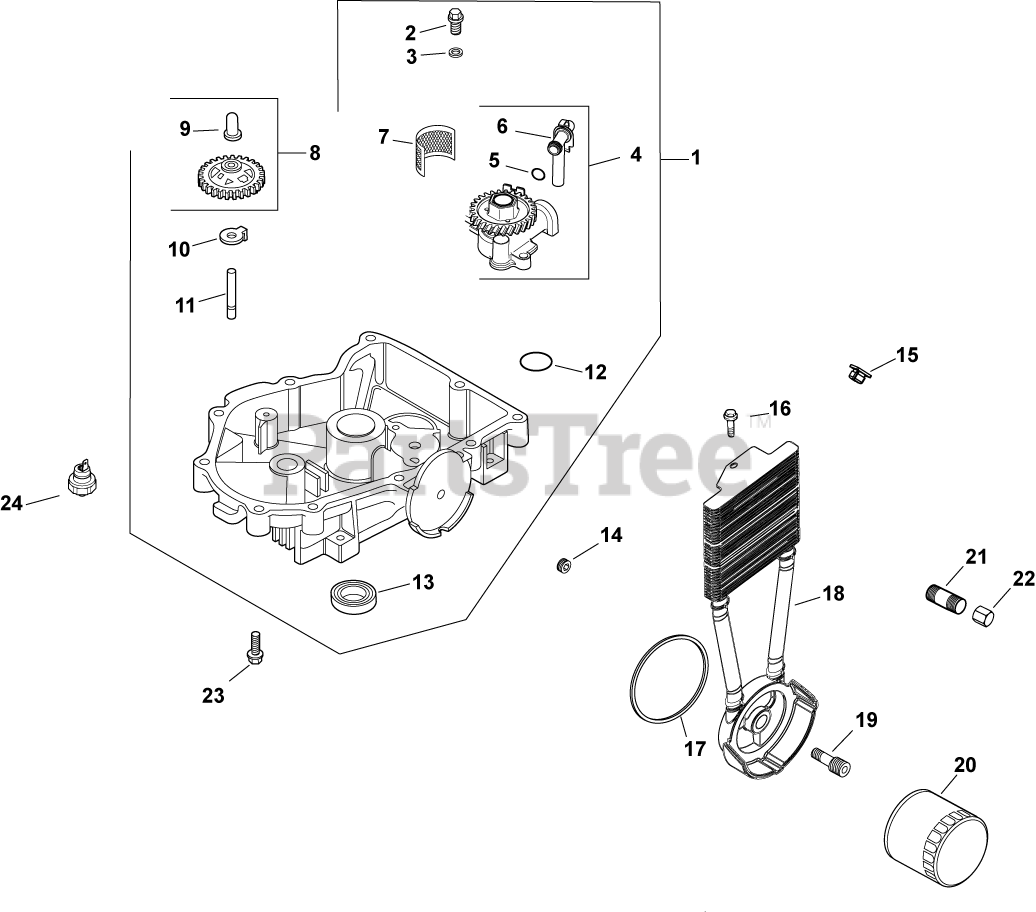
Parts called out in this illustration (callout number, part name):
1	PAN , OIL ASSEMBLY USE 24 199 32-S
2	SCREW,FLG THD FRM M6X1.0X25-(#25086395S)
3	WASHER, FLAT 6 MM
4	PUMP ASSEMBLY, OIL-USE 24 393 53-S
5	O-RING, OIL PICK-UP
6	KIT, OIL PICK-UP TUBE
7	SCREEN, OIL
8	KIT, GOVERNOR GEAR W/PIN
9	PIN, GOVERNOR REGULATING
10	TAB, LOCKING
11	SHAFT, GOVERNOR GEAR
13	SEAL, OIL
14	PLUG, PIPE CTSK 3/8"
15	NUT, PLASTIC (KM)-USE 25 100 37-S
16	SCREW, TAP M6X1.7X18
17	O-RING, OIL COOLER
18	KIT, OIL COOLER
19	NIPPLE, OIL FILTER
20	OIL FILTER
21	NIPPLE, PIPE
22	CAP, PIPE
23	SCREW, FLG M8X1.25X45
24	SENSOR, OIL PSI
